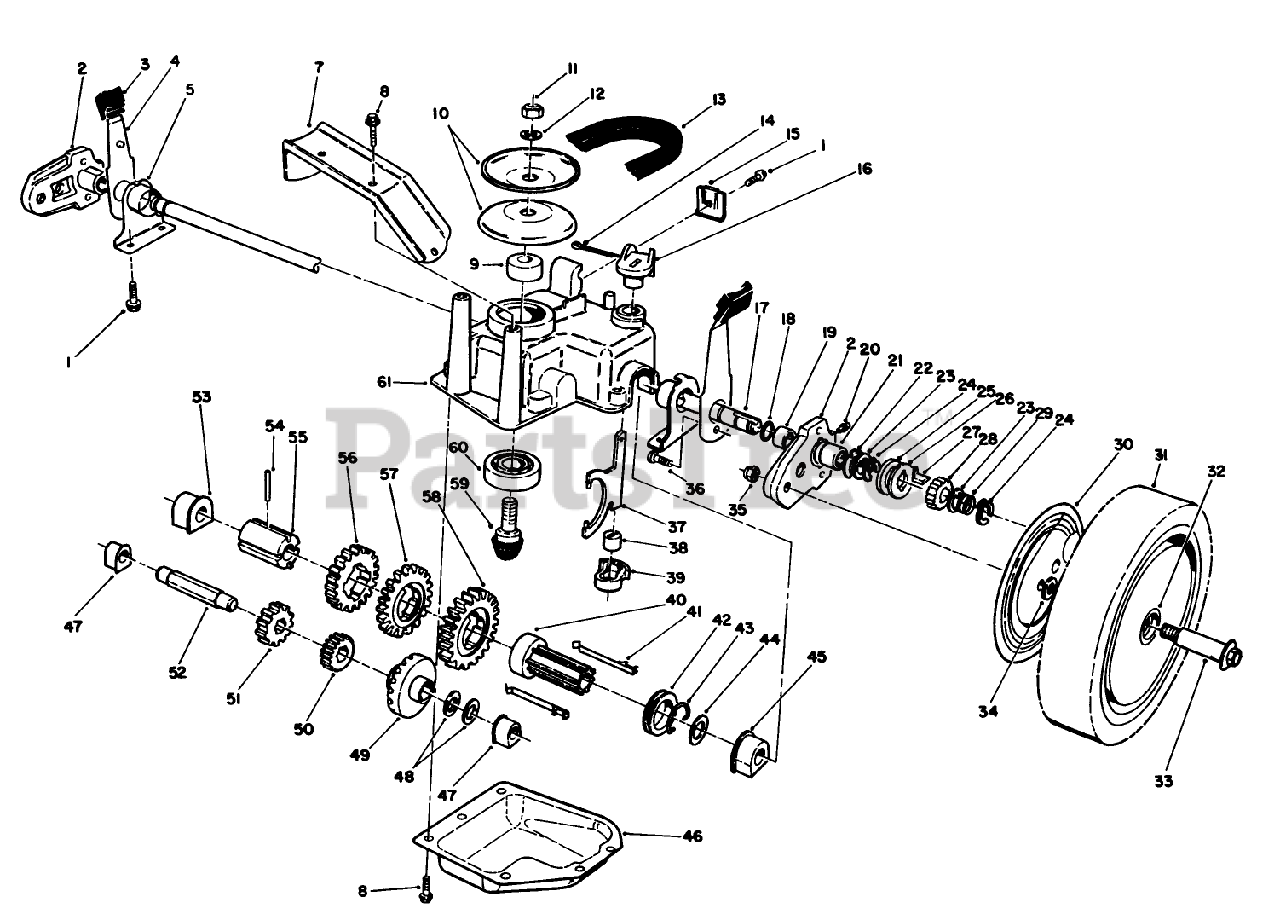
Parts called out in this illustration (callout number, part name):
1	SCREW-HWHTF
3	KNOB-ARM
4	SPRING ARM ASM
5	CAP-END
8	SCREW-HWHTF
9	SPACER
11	NUT-HEX
12	WASHER-FLAT
13	V-BELT
14	PIN-COTTER
15	CABLE CLAMP
17	SHAFT-OUTPUT
18	O-RING
19	BUSHING
20	FITTING-GREASE
22	WASHER-ARM, PIVOT
23	WASHER-THRUST, KEYED
24	RING-RETAINING,CLIP
25	RING-FRICTION
26	WASHER-CLUTCH
27	KEY-ROCKING, LH
28	GEAR-PINION
29	SPRING-COMPRESSION
30	WHEEL COVER (BLACK)
32	BUSHING
33	WHEEL BOLT
34	WASHER
36	SCREW-HSH, THREAD FORMING
37	YOKE-SHIFT
38	BUSHING-YOKE
39	RETAINER-FORK, SHIFT
43	CLIP-SPRING
44	WASHER-PLAIN
45	BUSHING-OUTPUT
47	BUSHING
48	WASHER-THRUST
50	PINION-20T
51	PINION-25T
53	BUSHING
54	PIN-SPRING
55	SLEEVE-GEAR
56	GEAR-39T
57	GEAR-44T
58	GEAR-49T
60	BEARING-BALL
61	CASE-GEAR, UPPER
